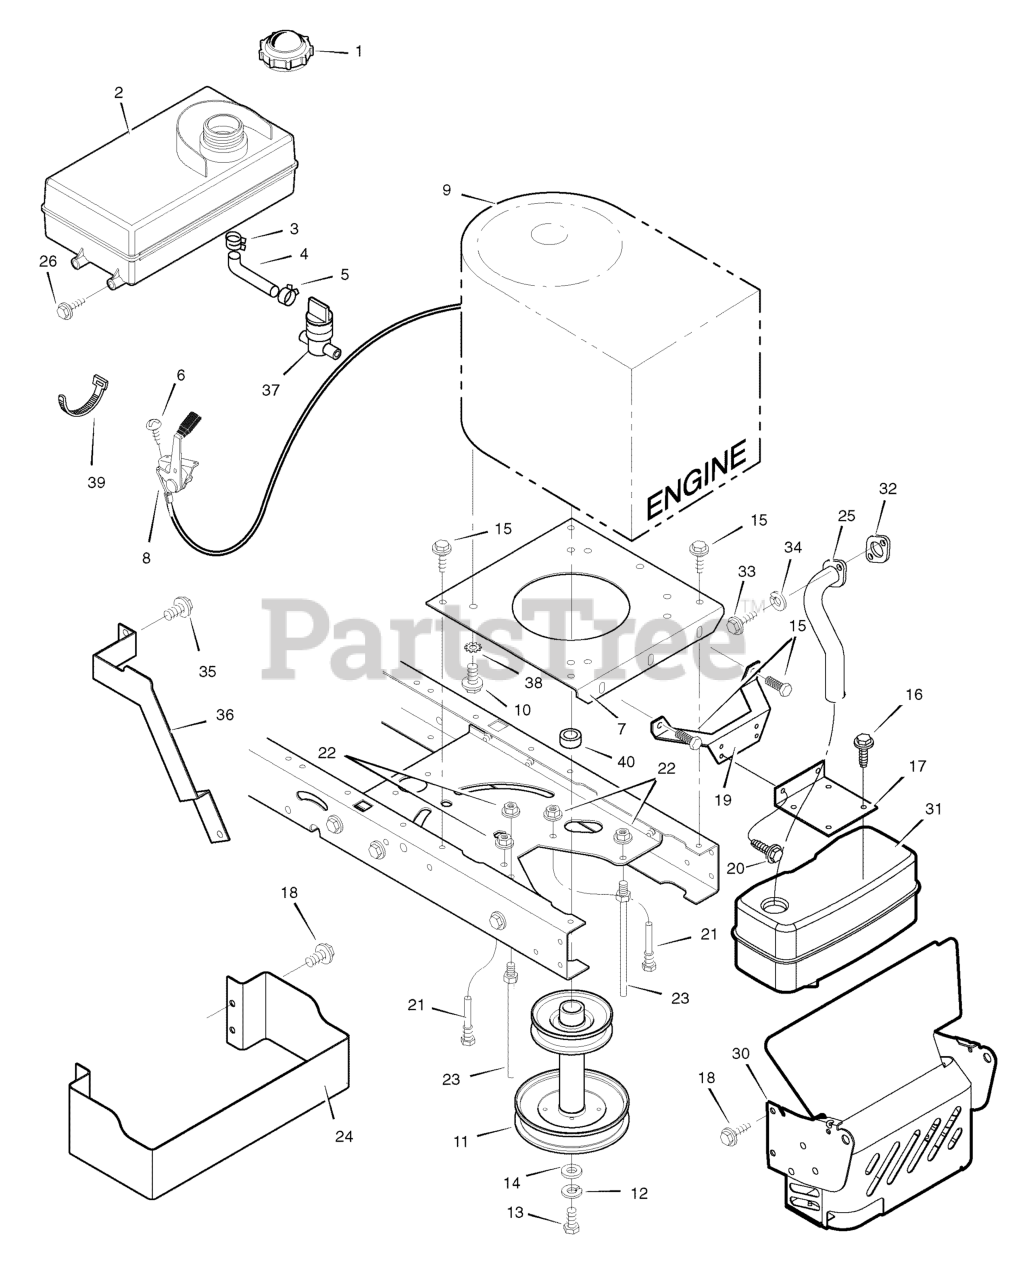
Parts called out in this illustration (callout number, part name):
1	Fuel Cap
2	Fuel Tank
3	Hose Clamp
4	FUEL LINE (Cut to length)
5	Hose Clamp
7	Plate, Engine
8	Throttle Control
9	Engine, Briggs & Stratton *
10	BOLT, Engine Mount
11	Stack Pulley Assembly
12	LOCKWASHER
13	BOLT, Hex
17	BRACKET, Muffler
19	BRACKET, Muffler Mount
21	GUIDE, Belt
22	NUT, Flange
23	GUIDE, Belt
24	GUARD, Heat Shield
25	Exhaust Tube, Single
30	SHIELD, Heat
35	BOLT, Washer Hex Head
36	GUARD, Exhaust Pipe
37	Valve, Fuel Shut-Off
38	WASHER, 3/8-5/8 Star
39	Strap, Tie
40	SPACER, Engine
